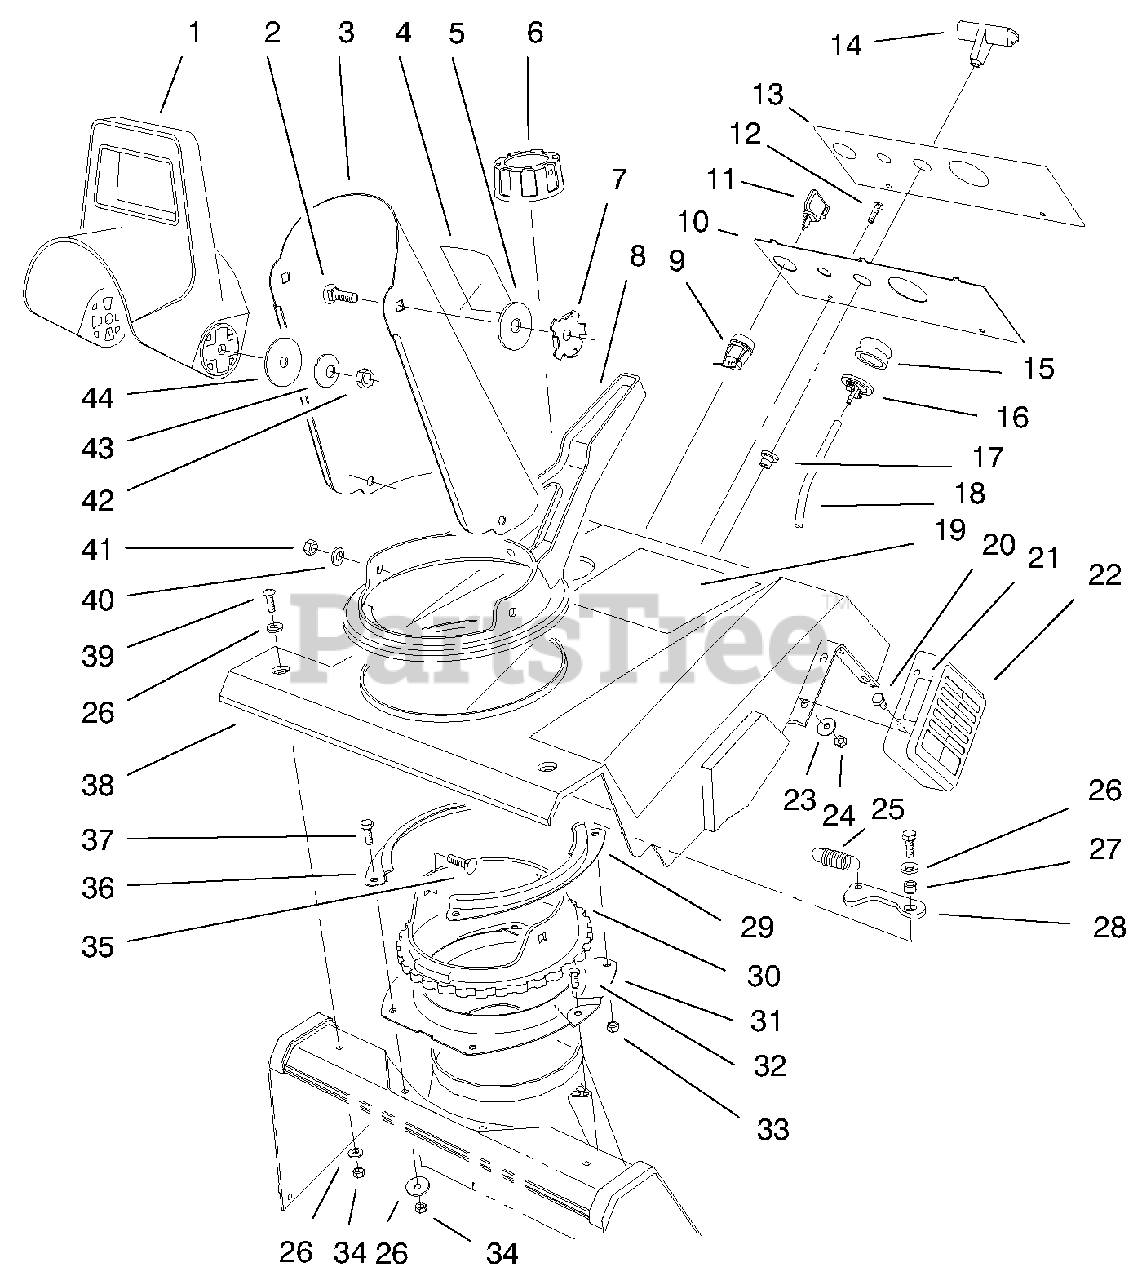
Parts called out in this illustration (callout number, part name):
1	Deflector
2	Screw-CARR
3	Chute ASM
4	Decal-Danger
5	Washer-Rubber
6	Gas Cap ASM
7	Plate-Friction
8	Handle-Chute
9	Switch-Key
10	Panel-Control (Model 28220)
10	Panel-control (Model 28222)
11	Key-Ignition
12	Screw-Tf Acorn Hd
13	Decal-Control Panel (Model 28220)
13	Decal-Control Panel (Model 28222)
14	Handle-Starter
15	Bulb-Primer
16	Body-Primer
17	Guide-Rope
18	Hose-Primer
19	Decal-320e (Model 28222)
19	Decal-320 (Model 28220)
21	Decal-Hot
22	Guard-Muffler
23	Washer-Flat
24	Nut-Lock
25	Spring-Detent
26	Washer-Flat
27	Spacer-Rotor Blade
28	Arm-Detent
29	Retainer-Chute Ring
30	Ring-Chute
31	Ring-Chute Support
32	Screw
33	Nut-Lock
34	Nut-Lock
35	Screw-CARR
36	Retainer-Chute Ring
37	Screw-HH
38	Shroud-Upper
39	Screw-PPH
40	Washer-Flt
42	Nut-Lock
43	Washer-Lock
44	Washer-Flat
